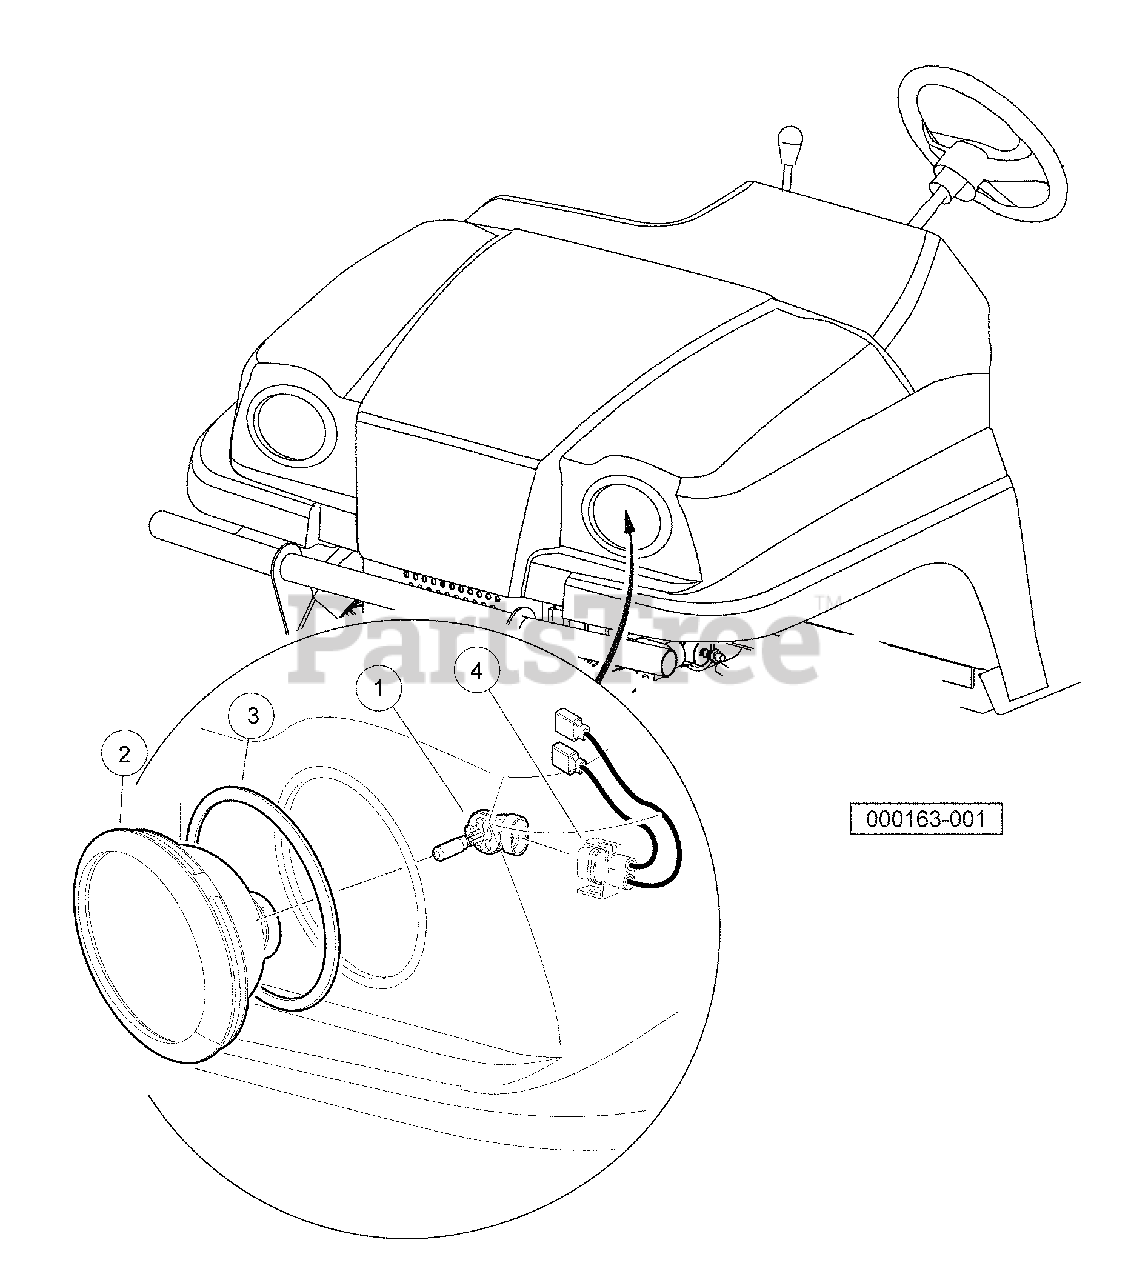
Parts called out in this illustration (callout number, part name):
1	Assembly, Headlight
2	Spacer, Headlight, Oval
3	Harness, Headlight
4	Bulb, Headlight, Oval
